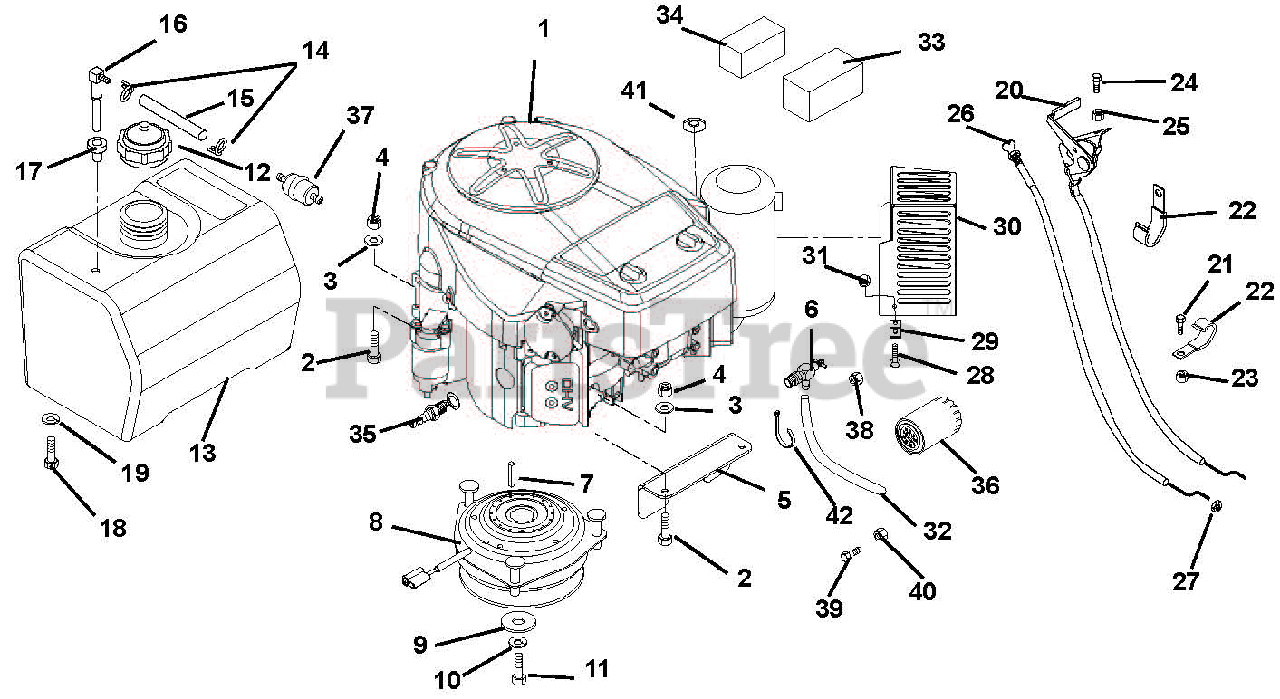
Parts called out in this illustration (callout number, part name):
1	Engine, 17 HP Kawasaki
1	Engine, 15 HP Kawasaki
1	Engine, 13 HP Kawasaki
2	Bolt-Hex .31-18 x 1.75 Grade 5
3	Washer-Locking .31 x .078 Regular
4	Nut-Hex .31-18
5	Bracket, Clutch
6	Valve, Oil Drain
7	Key-Square .25 x 1.25 x 25 SAE 8630 OR SAE 1035
8	Clutch, Electric
9	Washer-Flat-Steel .469 x 2.00 x .25
10	Washer-Locking .44 x .109 Regular
11	Bolt-Hex .44-20 x 3.00 Grade 5
12	Cap, Fuel
13	Tank, Fuel
14	Clamp-Hose Wire .49/.51 x .116
15	Gas Line-Bulk .25 I.D.
16	Fitting, Tank
18	Bolt-Hex .38-16 x .75 Grade 5
19	Washer-Locking .38 x .094 Regular
20	Cable, Throttle-with Liner
20	Cable- Throttle-with Liner
21	Bolt-Hex .31-18 x .75 Grade 5
23	Nut-Locking-Nylon .312-18
24	Screw-Machine 10-24 x .75 Hex Washer Head
25	Nut-Locking-Nylon 10-24 with Insert
26	Control, Choke
27	Nut-Jam .375-24
28	Bolt-Hex .31-18 x .75 Grade 5
29	Bracket, Muffler Guard
30	Guard, Muffler
31	Nut-Locking-Center .31-18
32	Tube, Oil Drain
33	Filter, Air Paper
34	Filter, Air Foam
35	Spark Plug
36	Filter, Oil
37	Fuel Filter- Kawasaki
38	Nut-Locking-Center .31-18
39	Bolt-Hex .38-16 x .75 Grade 5
40	Nut-Locking-Center .38-16
41	Washer-Flat-Steel .38 x .87 x .179
42	Cable Tie
